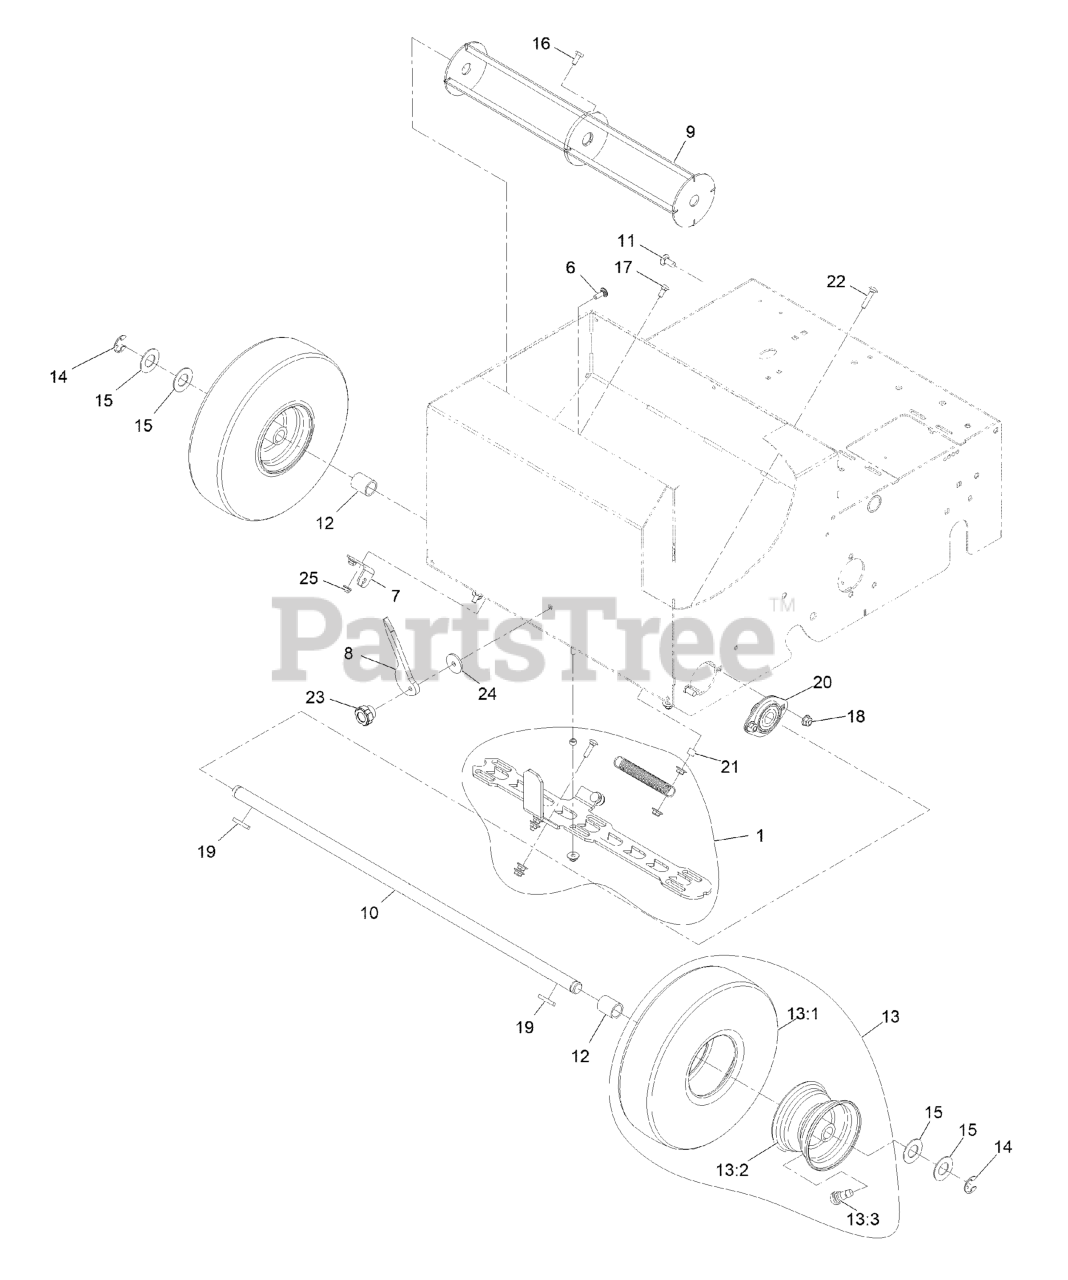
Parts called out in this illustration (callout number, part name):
1	SEED GATE KIT
6	BOLT-CARR
7	BRACKET-FLOW, SEED
8	GAUGE-FLOW, SEED
10	AXLE-FRONT
11	SCREW-CARR
13	WHEEL ASM
13:2	WHEEL-RIM
13:3	VALVE
15	WASHER-FLAT
16	SCREW-HH
17	SCREW-CARR
18	NUT-HF, NI
19	KEY-SQUARE
20	BEARING
22	SCREW-CARR
23	KNOB-CHUTE
24	WASHER
